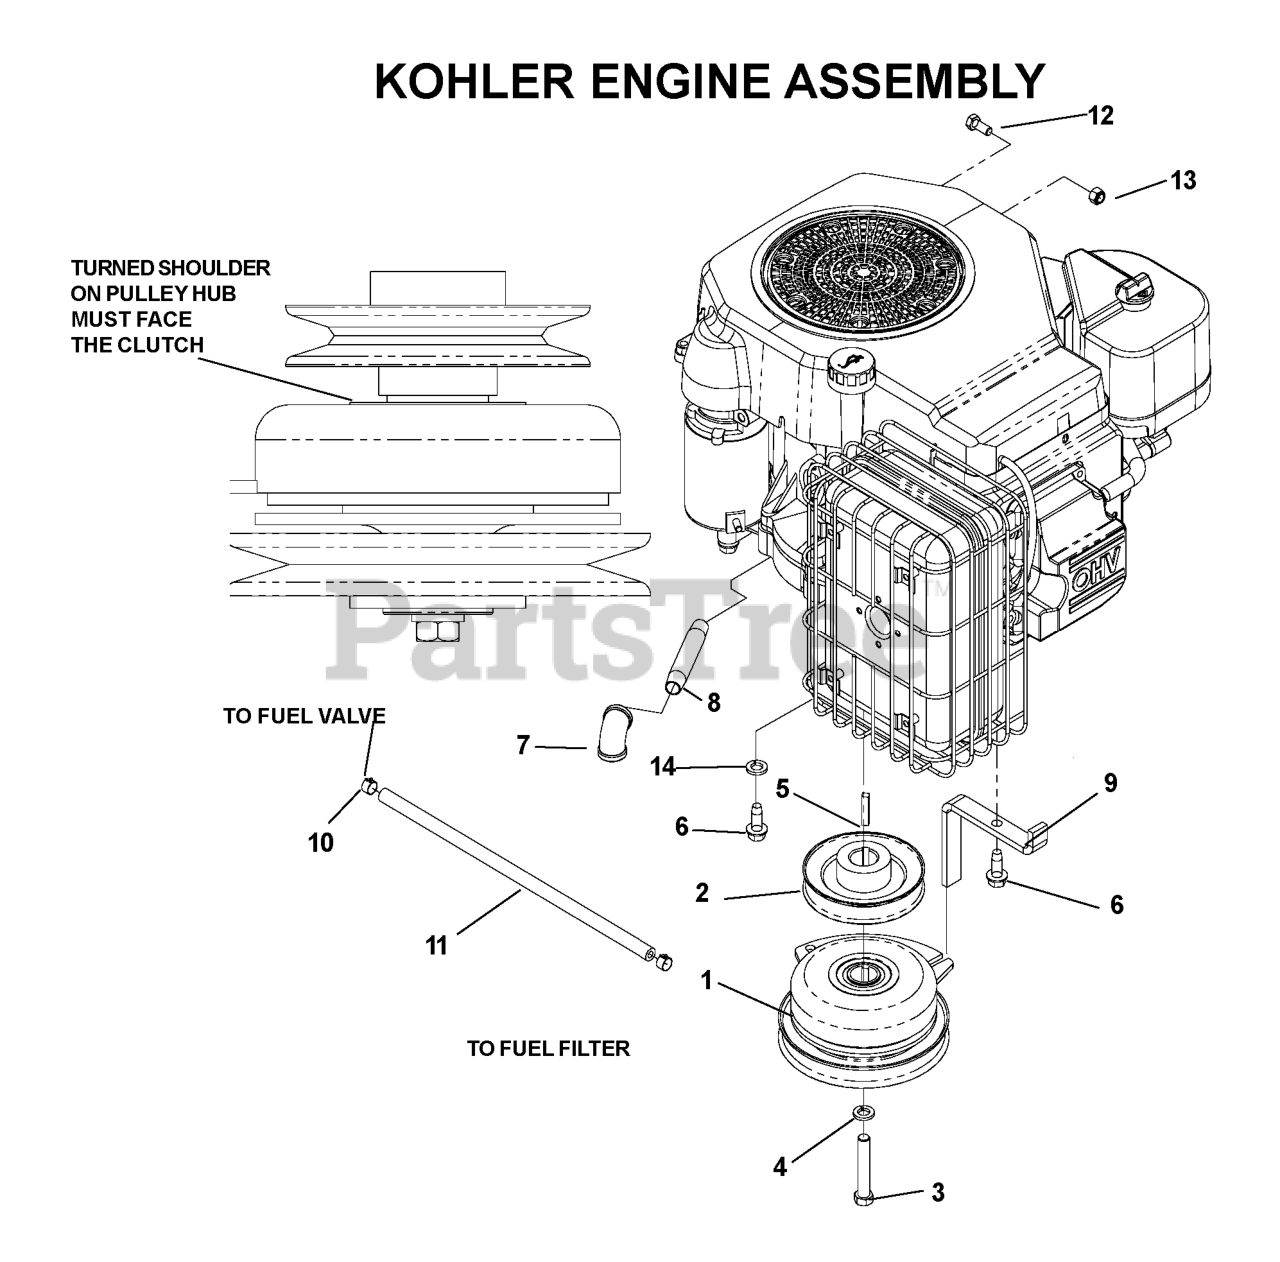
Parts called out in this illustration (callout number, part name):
3	BOLT 7/16F X 2 1/2
4	WASHER 7/16 LOCK
5	KEY 1/4 SQ X 1 1/8
6	BOLT 3/8-16 X 1.0
7	90 DEG.ELBOW 3/8NPT
8	PIPE, 3/8 NPT X 4"
9	CLUTCH TIE DOWN
10	HOSE CLAMP
11	FUEL LINE 14"
12	HCS 5/16C X 3/4
13	NUT 5/16 NYLOC
14	WASHER
539105637	CLUTCH HARNESS
539107516	KOHLER PIGTAIL-CV490S
539108120	JAM NUT 1/4C (2 2 PW01)
